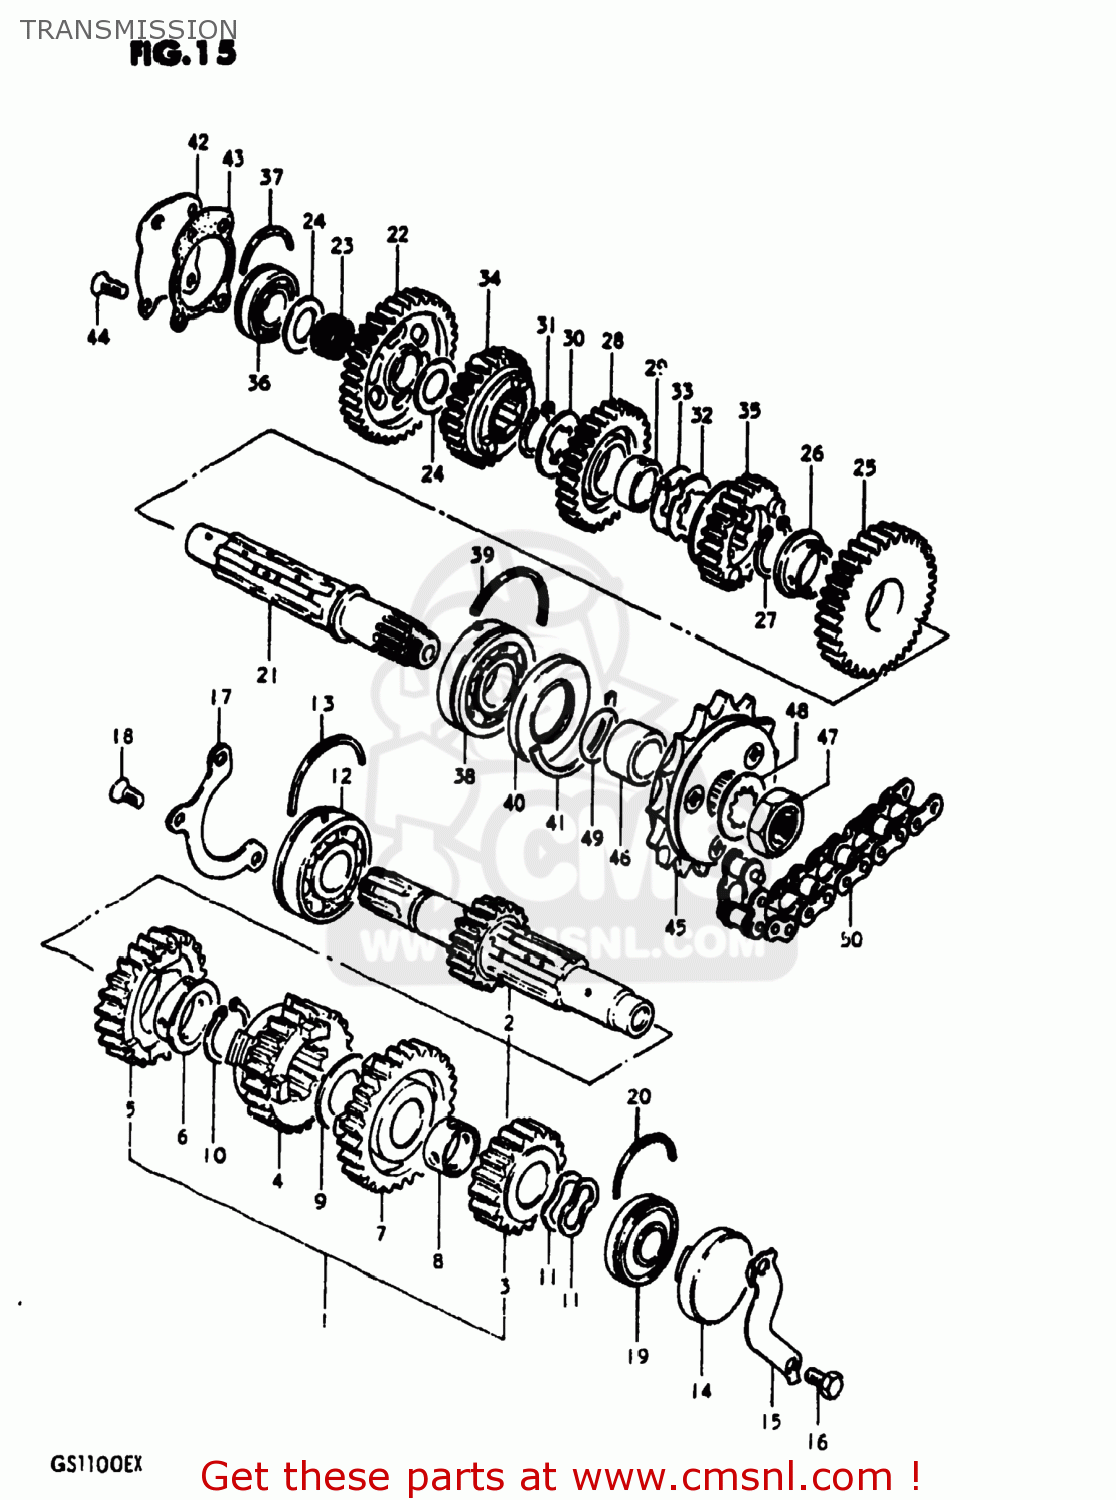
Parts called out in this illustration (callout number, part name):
1	SHAFT,COUNTER
2	SHAFT,COUNTER
3	GEAR,SECOND DRIVE
4	GEAR,3RD DRIVE(NT:21)
5	GEAR,FOURTH DRIVE
6	BUSH(28X32X2)
7	GEAR,FIFTH DRIVE
8	BUSHING
9	WASHER
10	CIRCLIP
11	WASHER
12	BEARING(25X62X17)
13	C-RING
14	PLUG
15	RETAINER,CL PUSH ROD OIL SEAL
16	BOLT
17	RETAINER,CNTR SHAFT BEARING
18	SCREW
19	BEARING(20X47X14)
20	C RING
21	SHAFT,DRIVE
22	GEAR,FIRST DRIVEN (NT:35)
23	BEARING(20X24X10).8
24	WASHER
25	GEAR,SECOND DRIVEN
26	BUSH(28X32X2)
27	CIRCLIP
28	GEAR,THIRD DRIVEN
29	BUSH,3RD DRIVEN GEAR
30	WASHER,LOCK
31	CIRCLIP
32	WASHER,LOCK
33	WASHER
34	GEAR,FOURTH DRIVEN
35	GEAR,FIFTH DRIVEN
36	BEARING
37	C RING
38	BEARING(25X62X17)
39	C-RING
40	SEAL,OIL(32X62X7)
41	C RING
42	PLATE,DRIVE SHAFT
43	GASKET,DRIVESHAFT PLATE (MCA)
44	SCREW
45	SPROCKET,ENGINE
46	SPACER(25X32X18.6)
47	NUT
48	WASHER
49	O RING(D:1,ID:24.5)
50	CHAIN ASSEMBLY,DRIVE
